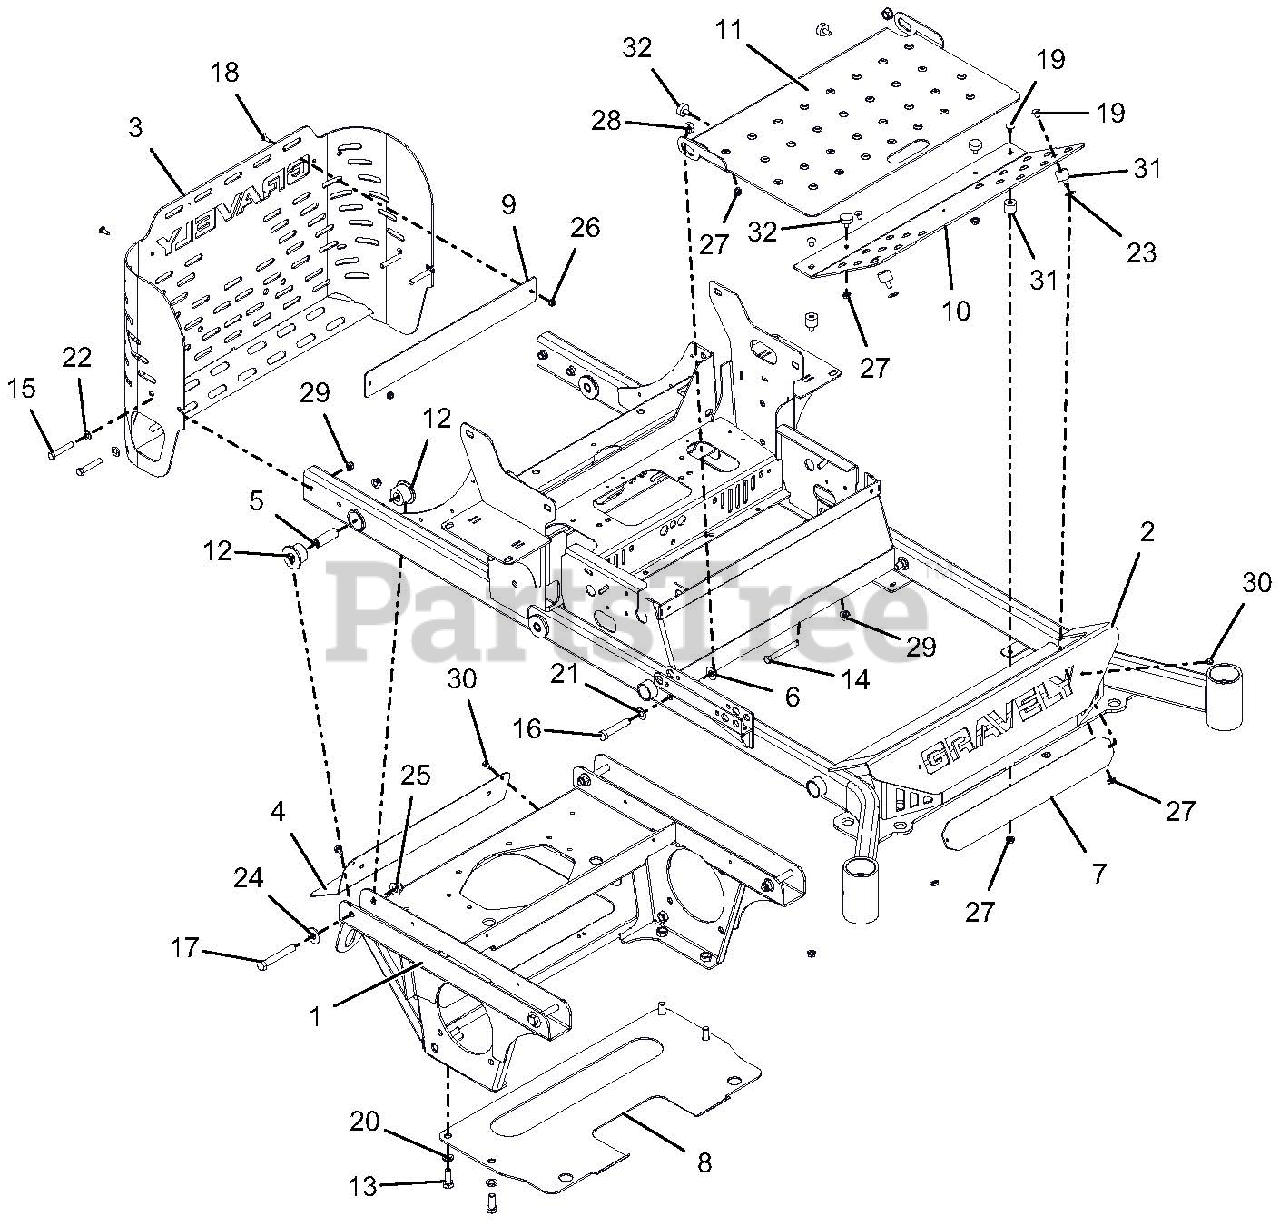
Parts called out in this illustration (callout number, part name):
1	PT200/400 AXLE/ENG FRM WMT-RED
2	52-60" PT400 FRAME W/DECALS
3	REAR BUMPER W/SAFETY DECALS
4	MUFFLER HEAT SHIELD - BLACK
5	BSHG-SLV .50X.75X2.23
6	BSHG-FLG .515X.750X.310X1.120
7	BUMPER LOGO BACKING PLATE -BLK
8	PLATE-TRANSMISSION SKID
9	LOGO BACKING PLATE - BLACK
10	FOOTREST - RED
11	INSPECTION PANEL - RED
12	BSHG-FLG .75X1.51X1.13X2.0 URE
13	@BLT-HEX .50-13X1.25 GR5 YWZC
14	@BLT-HEX .38-16X3.25 GR5 YWZC
15	@BLT-HEX .38-16X2.25 GR5 YWZC
16	@BLT-HEX .50-13X2.75 GR5 YWZC
17	@BLT-HEX .50-13X3.50 GR5 YWZC
18	@BLT-RDHDSQNK .25-20X.75 G5YZ
19	@BLT-RDHDSQNK .31-18X.50 G5YZ
20	@WSHR-LK .50X.125 REG YWZC
21	WSHR-FL-STL.531X1.00X.063 YWZC
22	@WSHR-FL-STL.406X.812X.065 YWZ
23	WSHR-FL-STL .328X.875X.062YWZC
24	@WSHR-FL-STL.563X1.38X.109YWZC
25	@NUT-LK-NYL-FLG .50-13 YWZC
26	@NUT-LK-NYL-FLG .25-20 YWZC
27	@NUT-SPNLK-FLG .312-18 YWZC
28	@NUT-LK-TOP-FLG .50-13 YWZC
29	@NUT-LK-NYL-FLG .38-16 YWZC
30	SCR-TAP .25-20X.50 HWH TR YWZ
31	BUMPER,STUD MNTD W/FEMALE INSR
32	BUMPER, RUBBER
